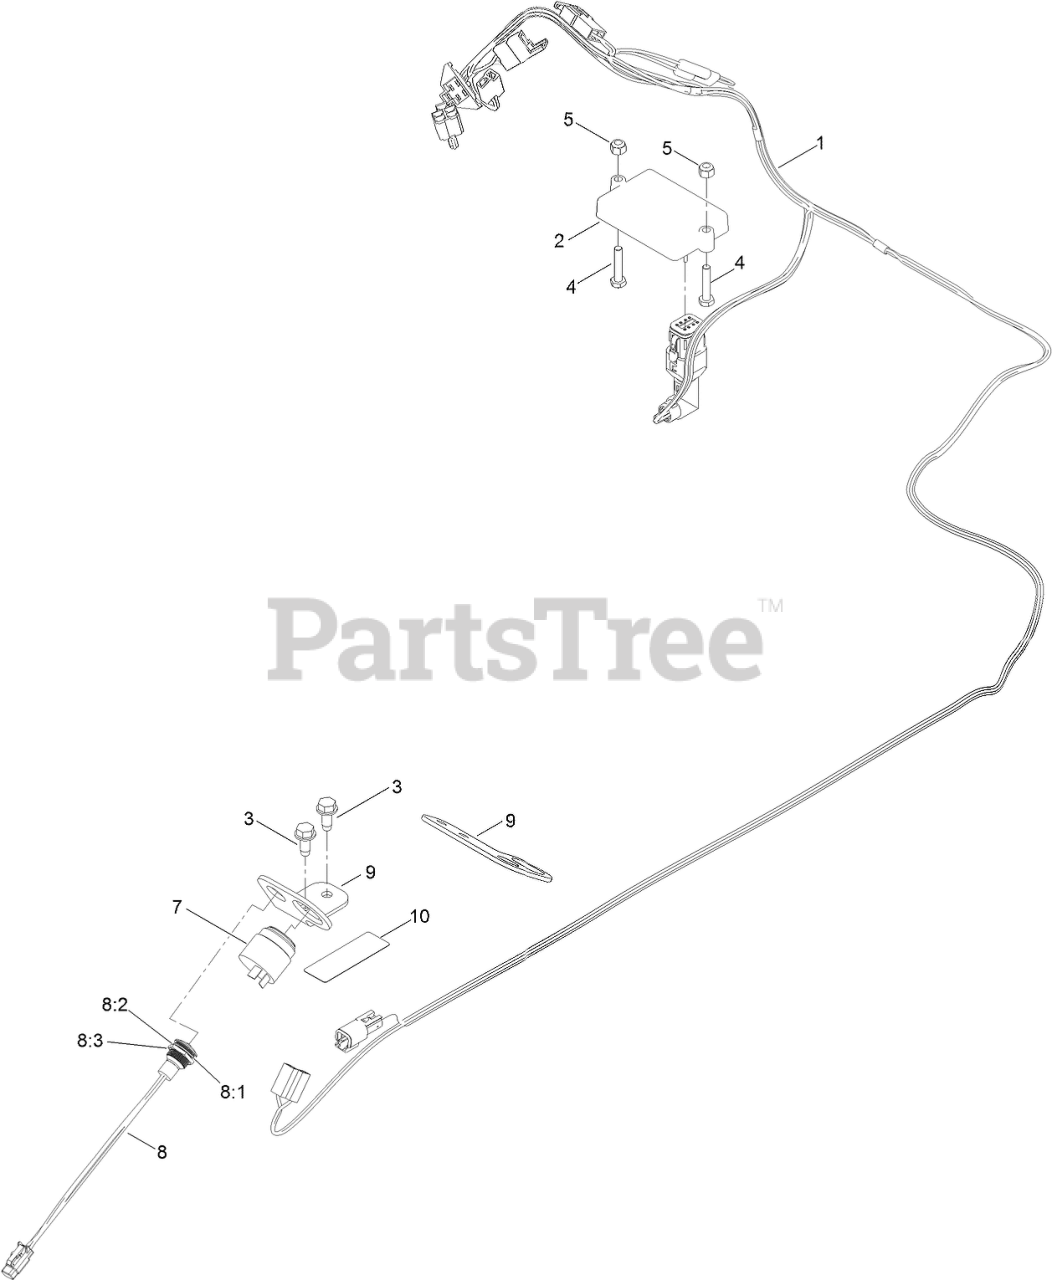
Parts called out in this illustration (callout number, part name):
1	HARNESS-WIRE, SLOPE SENSOR
2	CONTROLLER (FASM-TSM-0802)
3	SCREW-HWHTF
4	SCREW-HH
5	NUT-HEX
7	AUDIO ALARM ASM
8	RED LED INDICATOR LAMP ASM
8:1	GASKET-LED
8:2	WASHER-LOCKING
8:3	NUT-FIXING
9	BRACKET-LIGHT
9	BRACKET-LIGHT (MYRIDE)
10	DECAL-SLOPE SENSOR
